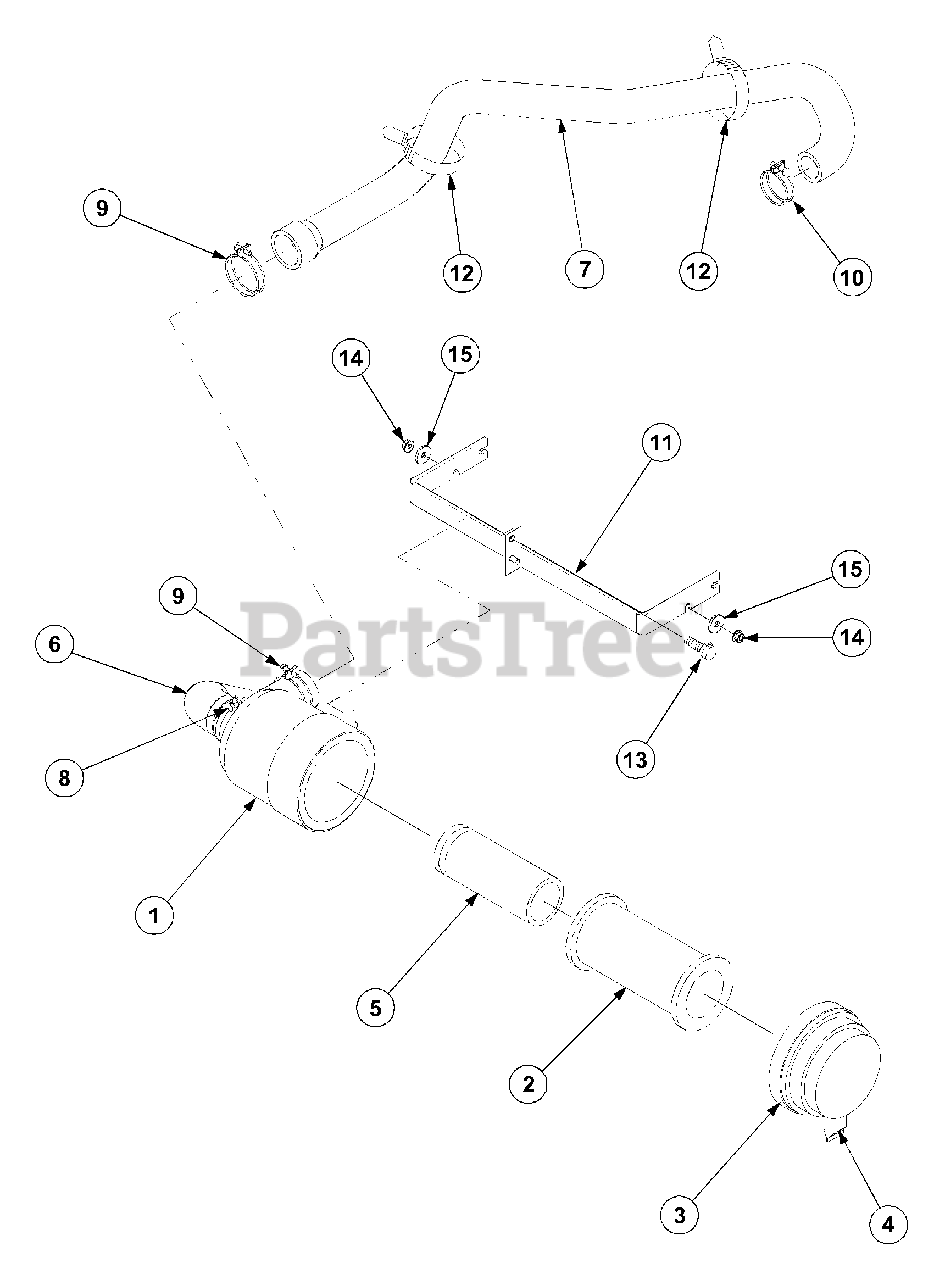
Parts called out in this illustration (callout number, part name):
4	Valve,Unloader
5	Element,Inner
13	Bolt,w/Washer
